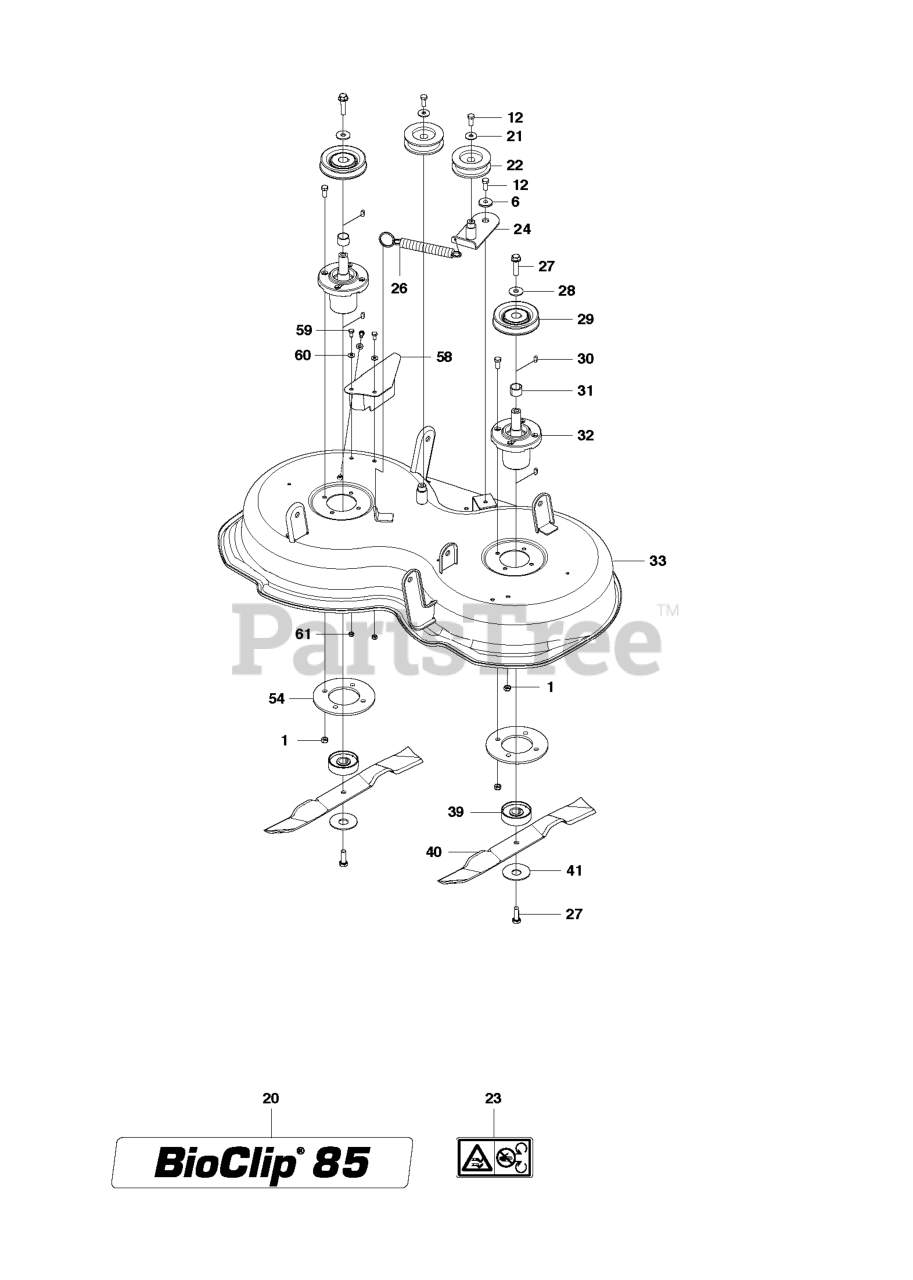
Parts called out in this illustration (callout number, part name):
1	LOCKNUT M8
6	WASHER
21	WASHER
22	PULLEY
32	BEARING HOUSING ASSY
41	WASHER
60	WASHER
61	LOCKNUT M6
